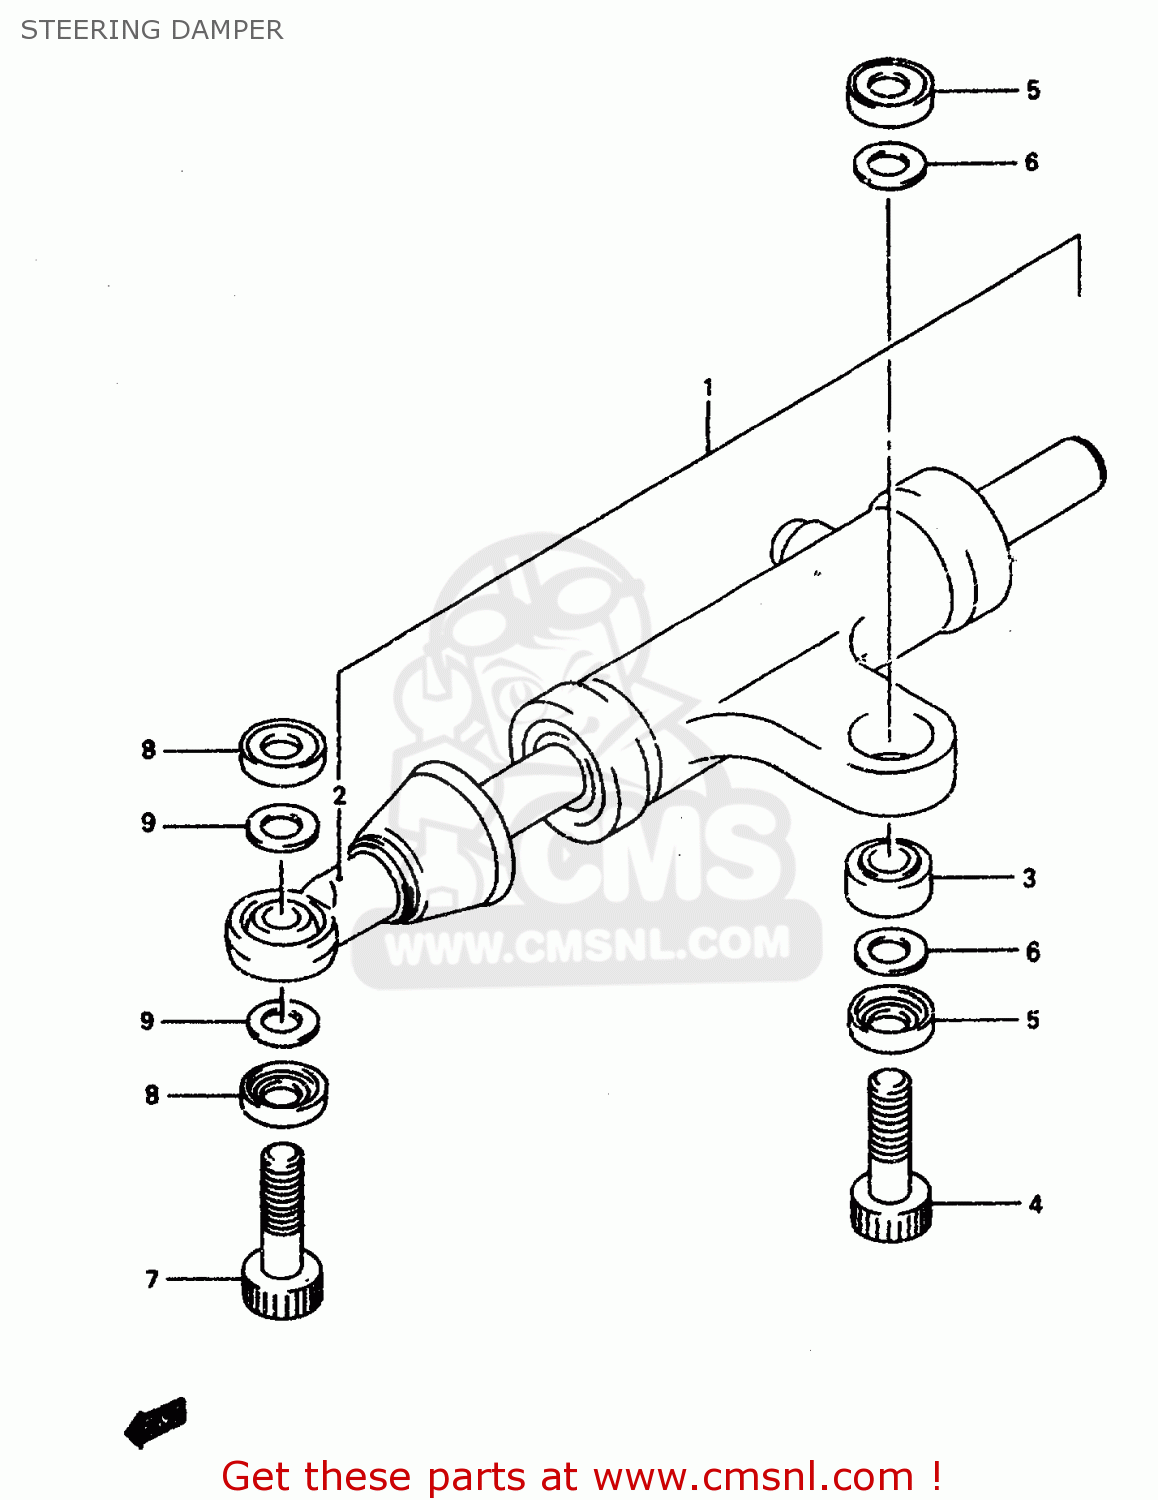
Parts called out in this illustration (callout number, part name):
1	DAMPER ASSY,STEERING
2	PILLOW BALL,ROD END
3	BEARING(8X17.5X11)
4	BOLT
5	6-1
6	SHIM
7	BOLT
8	9-1
9	SHIM
